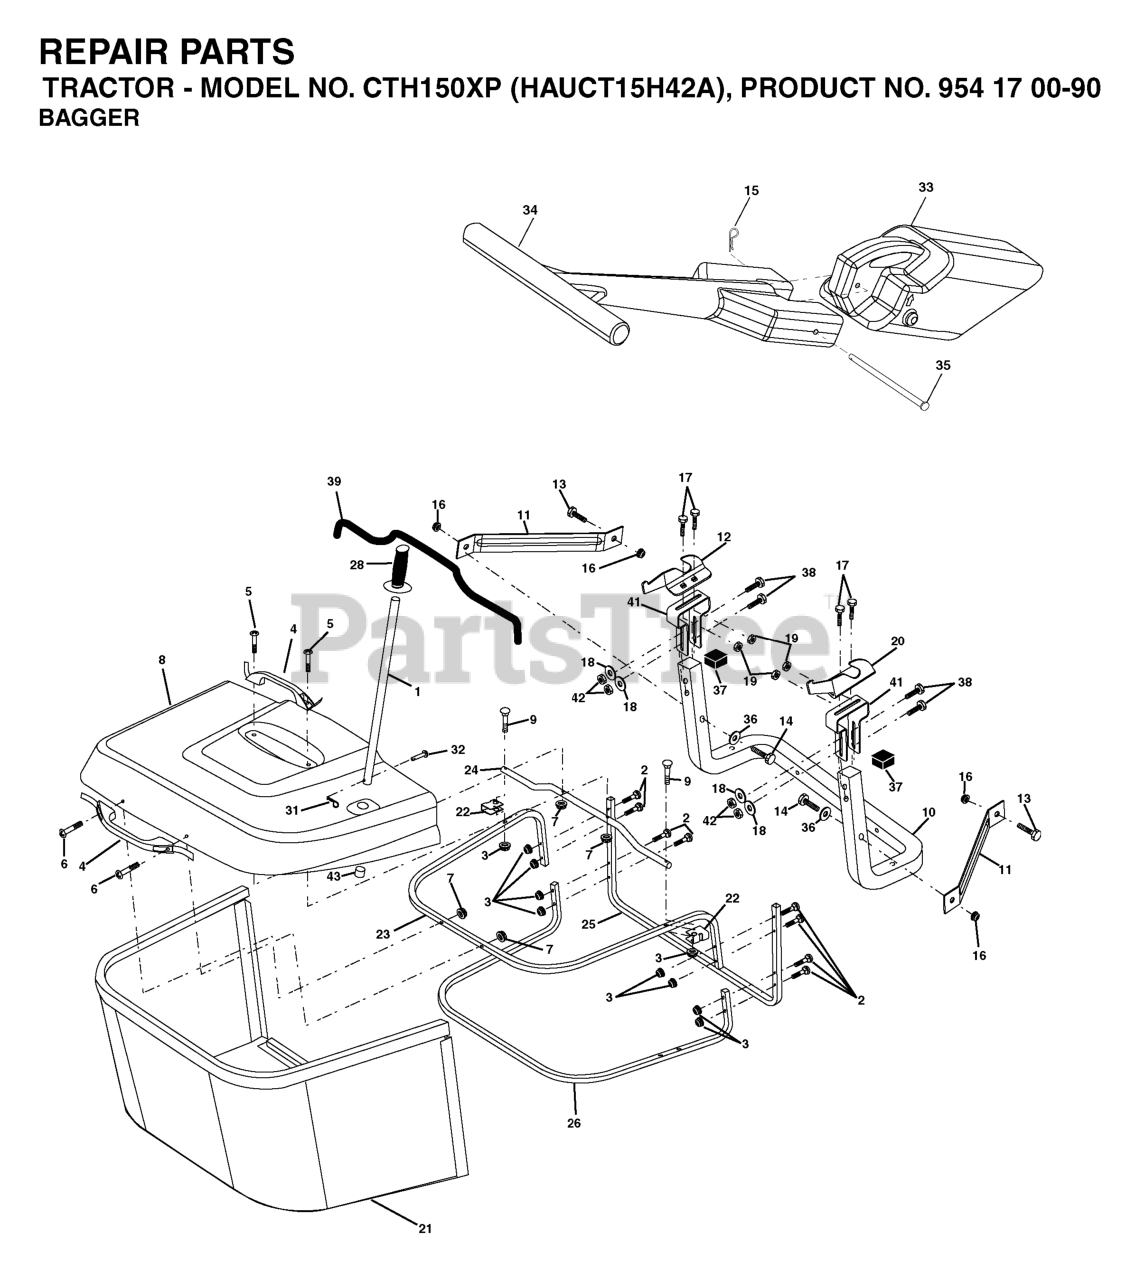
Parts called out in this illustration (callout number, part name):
1	TUBE HANDLE
2	Bolt Carriage 1/4-20 x 2.0 Gr.5
3	NUT T
4	HANDLE.BAGGER.W/LVRS.BLK.CRD
5	SCREW.PAN.HEAD
6	REPL BY 532 75 00-29
8	COVER.PNT.BGR.CRD.WSLOTS.MS668
9	Bolt Carriage 1/4-20 x 2.25d x Gr.5
10	TUBE
11	BRACKET.SUPPORT.UPPER.BAG.CRD
14	BOLT-HEX EAK
15	RETAINER-SPRNG RB
16	NUT LOCK FLG 3/8-16 UNC
17	RP BOLT 5/16-18 X3/4 ZN/YEL GR
18	WASHER M
19	NUT LOCK HEX FLANGE 5/16-18
20	BRACKET
21	GRASS BAG
22	BRKT.SIDE.BAG.CRD
23	TUBE.UPPER.BAG.CRD
24	TUBE.PIVOT.BAG.CRD.BLACK
26	TUBE.LOWER.BAG.CRD
28	GRIP.HANDLE.BLACK
31	RETAINER M
32	RIVET,DRILLED
33	MULCH PLUG, CTH150
34	HANDLE.MULCHER.92.CRD (2 2)
36	WASHER
37	Plug Support Bagger CRD
38	BOLT.5/16-18X2.5
39	SEAL.TRIM.37'
41	BRKT.VERT.ADJ.BAGGER.CRD
42	NUT.71038.31-18.HEX.NYLOCK
43	PLUG, TUBING END
